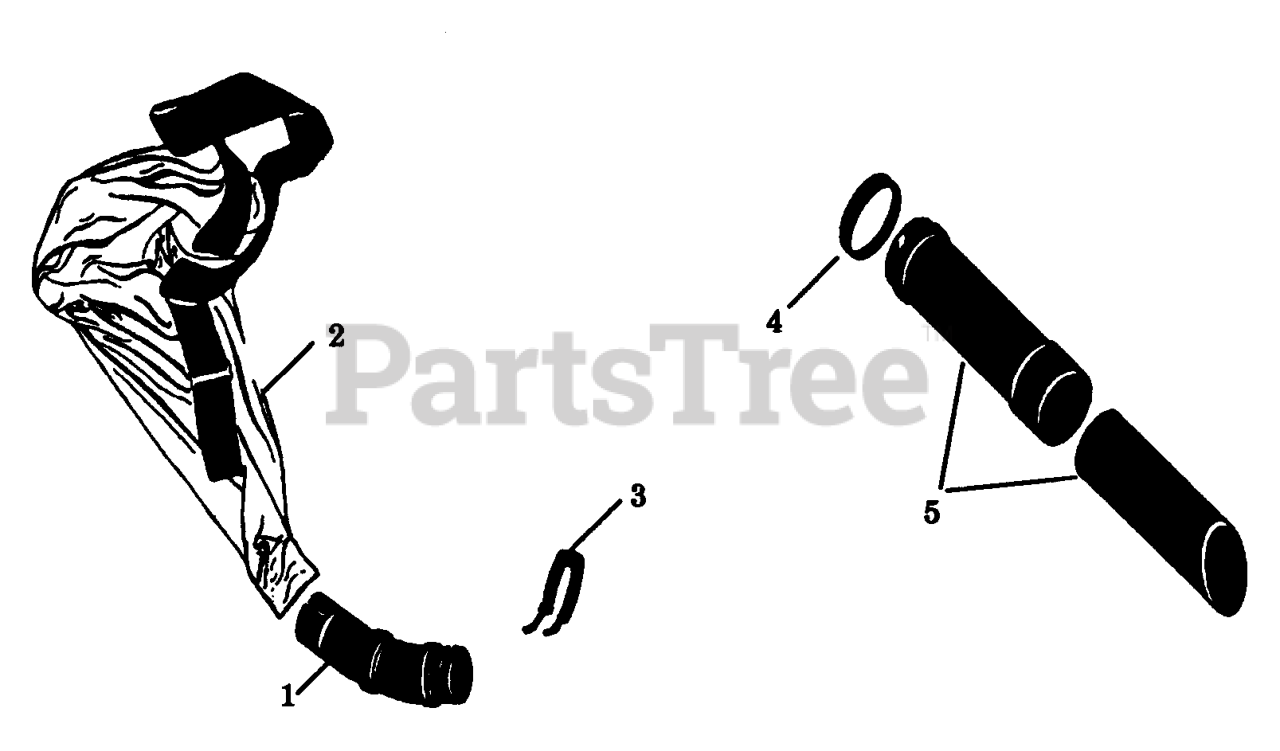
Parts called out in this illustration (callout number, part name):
1	ELBOW-VAC BAG
2	KIT-VAC. BAG
3	ASSY-HANDLE (REAR)
4	SPACER-RING
5	VAC TUBE SET
